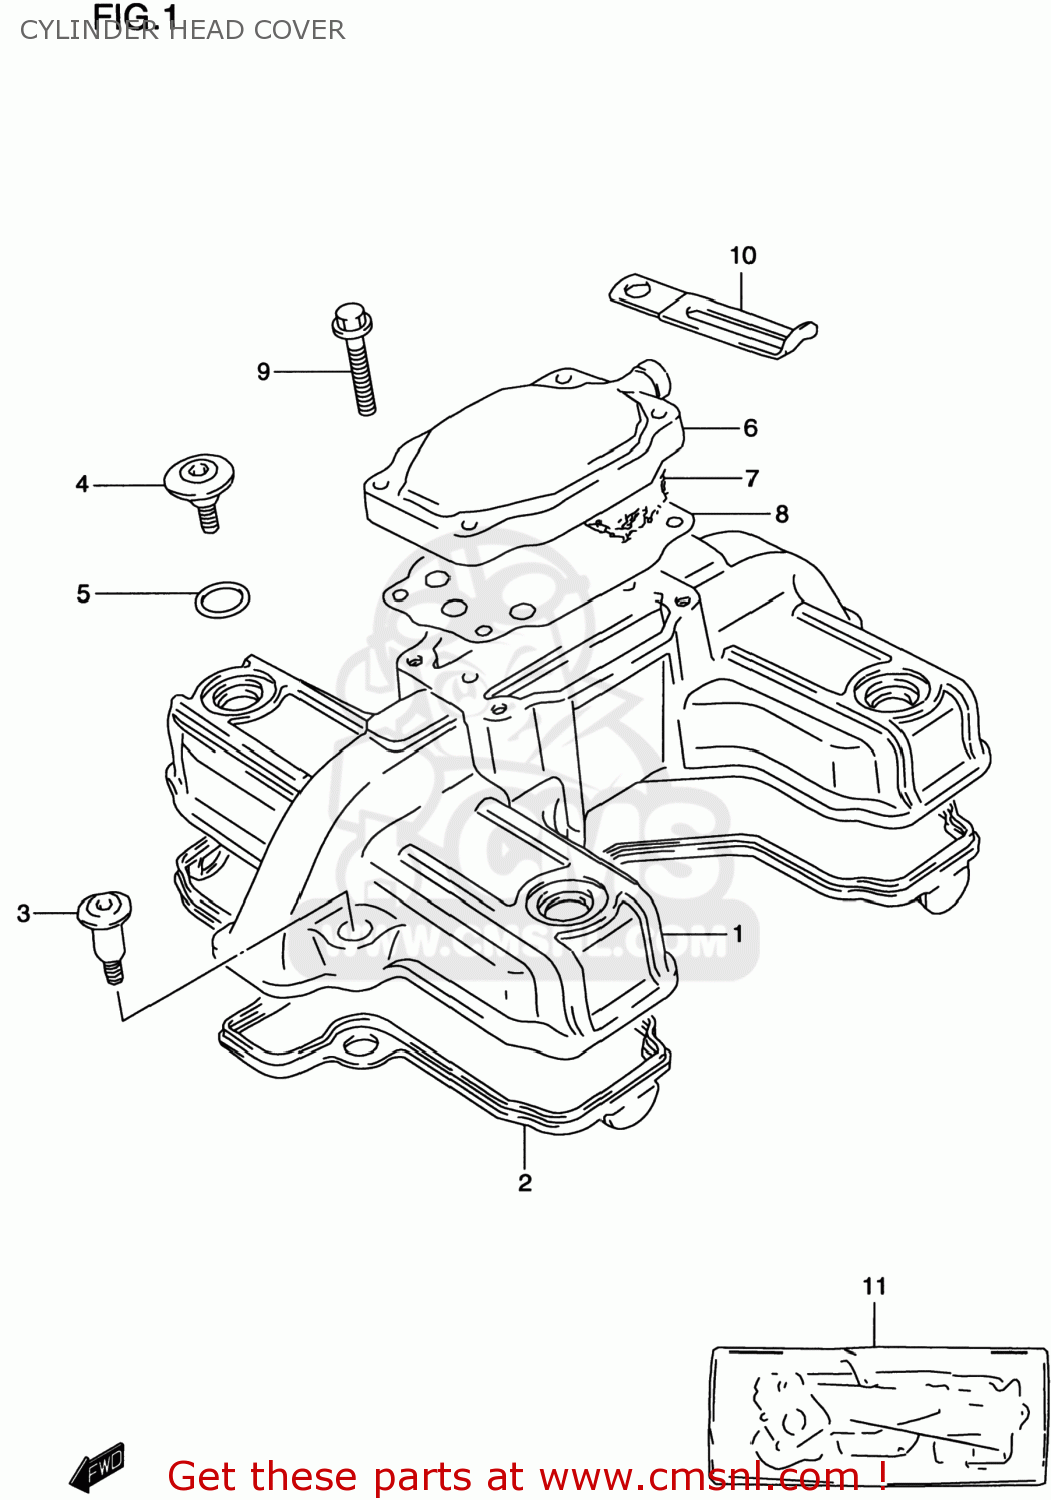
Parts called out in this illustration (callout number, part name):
1	COVER,CYLINDER HEAD
2	GASKET,CYLINDER HEAD COVER (NAS)
3	BOLT(7X31)
4	BOLT(7X17.5)
5	O RING(D:1.9,ID:14.5)
6	COVER,BREATHER
7	SEPARATOR,OIL BREATHER COVER
8	GASKET,BREATHER COVER (NAS)
9	BOLT
10	CLAMP(L:65)
11	GASKET SET (NAS)
